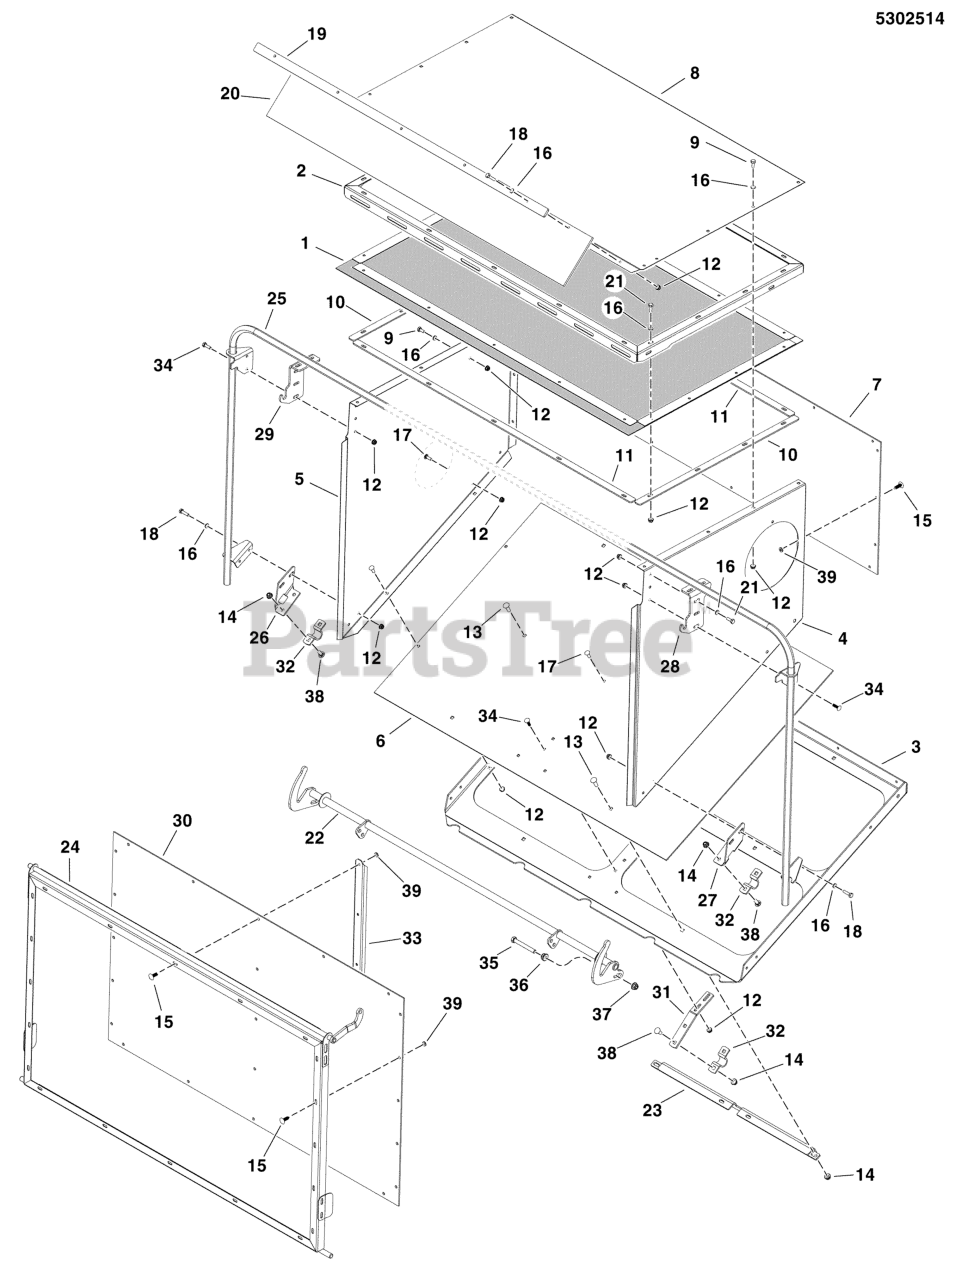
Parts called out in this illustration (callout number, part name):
1	SCREEN, ASM, COLLECTOR
2	WELD, SCREEN FRAME - BLK
3	WELD, SUBFRAME, HOPPER - BLK
4	PANEL, RIGHT, 14FT HOPPER - BLK
5	PANEL, LEFT, 14FT HOPPER
6	PANEL, BOTTOM, 14FT HOPPER
7	PANEL, FRONT, 14FT HOPPER
8	PANEL, TOP, 14FT HOPPER - BLK
9	HHCS, 1/4-20 X 0.625, GR5, ZINC/CLEAR
10	STRIP, SCREEN CLAMP, SHORT - BLK
11	STRIP, SCREEN CLAMP, LONG - BLK
12	NUT, 1/4-20 Hex Nylock Flange
13	BOLT, 5/16-18 X 1, CARRIAGE, GD5, CZ
14	NUT, 5/16-18 HEX NYLOCK FLANGE NUT
15	PUSH RIVET (TREE TYPE), BLACK
16	WASHER, 1/4 SAE
17	BOLT,1/4-20X0.750,GR5,STD NECK,SQ,ZC/CL
18	BOLT, 1/4-20 X 1" GD5 CZ
19	BAR, DEFLECTOR - BLK
20	DEFLECTOR, RUBBER, HOPPER
21	BOLT, 1/4"-20 X 3/4" GD5 YZ
22	WELD, LATCH ASSY, GATE - BLK
23	WELD, SUPPORT BRACKET - BLK
24	WELD, ASSY, GATE FRAME - BLK
25	WELD, ARCH ASSEMBLY - BLK
26	BRACKET, GATE LATCH, LEFT - BLK
27	BRACKET, GATE LATCH, RIGHT - BLK
28	PLATE, HINGE RIGHT, HOPPER - BLK
29	PLATE, HINGE LEFT, HOPPER - BLK
30	PANEL, HDPE, GATE, HOPPER
31	BRACE, CENTER, SHAFT - BLK
32	STRAP, ROCKER SHAFT
33	BRACKET, RIB, HOPPER - BLK
34	RHSSNB, 1/4C X1 GR5 Z
35	BOLT, 3/8-16 X 3" GD5 CZ
36	NUT, 3/8-16 Hex Large Serrated Flange
37	NUT, 3/8 - 16 HEX NYLOCK FLANGE
38	BOLT, 5/16-18 X 3/4, CARRIAGE, GD5, CZ
39	WASHER, #12 SAE FLAT, .25X.531X.051, CZ
